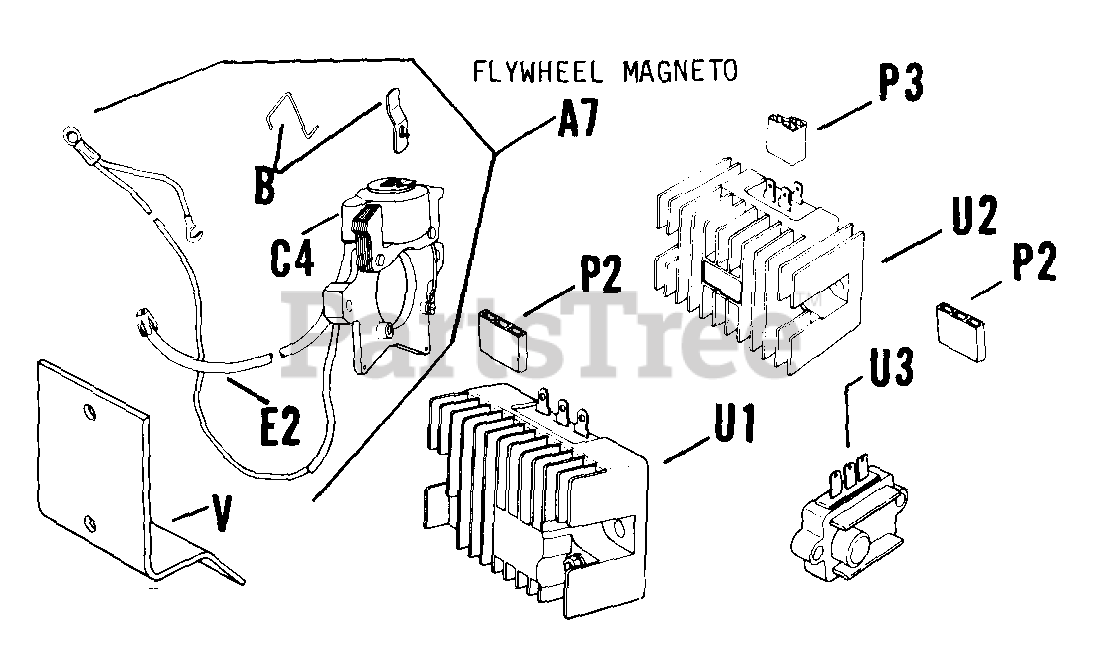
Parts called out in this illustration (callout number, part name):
P3	CONNECTOR - DISCONTINUED
U2	REGULATOR - USE 41 403 06
V	BRACKET - DISCONTINUED
